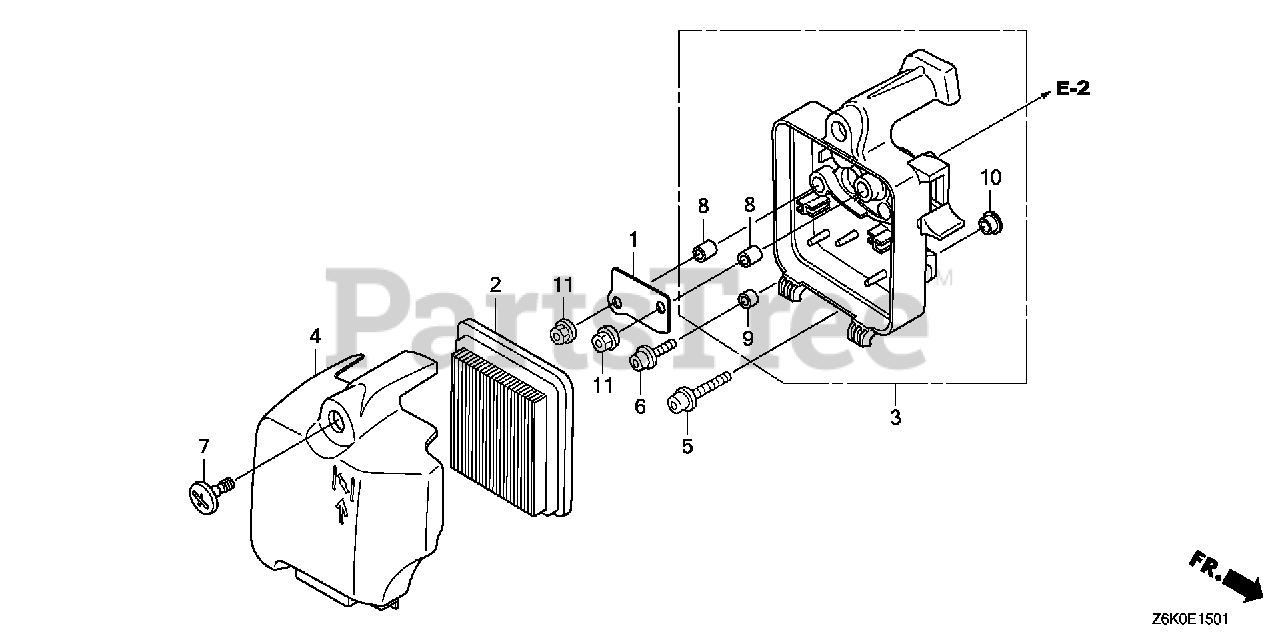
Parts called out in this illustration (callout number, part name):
1	PLATE, OIL TRAP
2	ELEMENT, AIR CLEANER
3	HOUSING, AIR CLEANER
4	COVER, AIR CLEANER
5	BOLT, SOCKET (5X25)
6	BOLT, SOCKET (5X16)
7	SCREW, SPECIAL (6X16)
8	COLLAR, AIR CLEANER HOUSING (A)
9	COLLAR, AIR CLEANER HOUSING (B)
10	COLLAR, AIR CLEANER HOUSING (C)
11	NUT, FLANGE (5MM)
